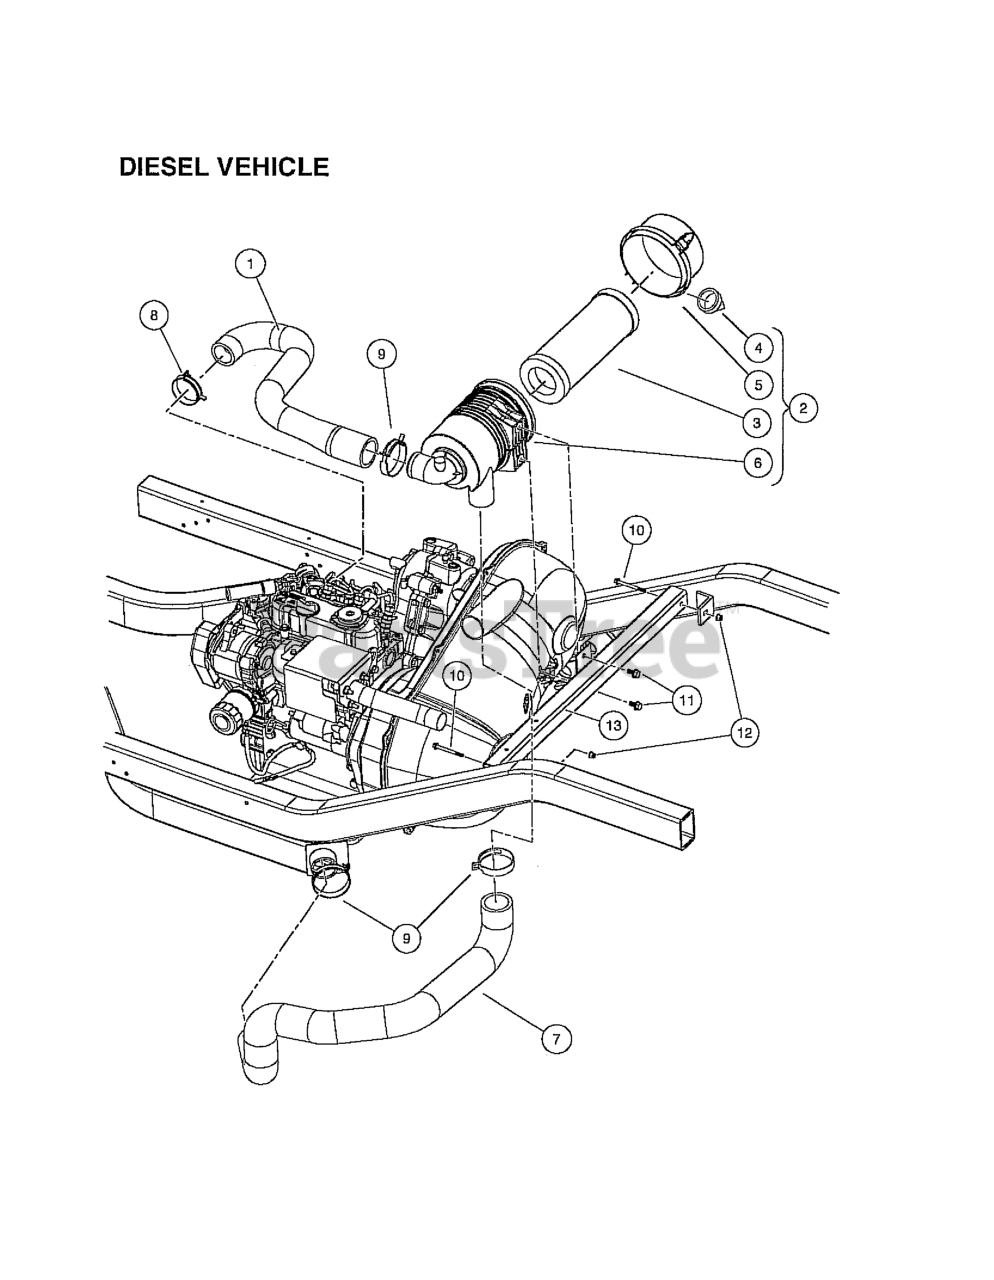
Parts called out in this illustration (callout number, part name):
1	HOSE, INTAKE, D722
2	FILTER, AIR, CANISTER, 5IN
3	ELEMENT, FILTER, AIR, 5 IN
7	HOSE, INTAKE, PRIMARY
8	CLAMP, HOSE, CTB 55MM
9	CLAMP, HOSE, CTB 64MM
10	BOLT-M6X1.0X65 HEX FL HD, BLK
11	BOLT FLG, M8X1.25X16 LOCTITE
12	NUT FLG, M6 X 1.0 NYLON
